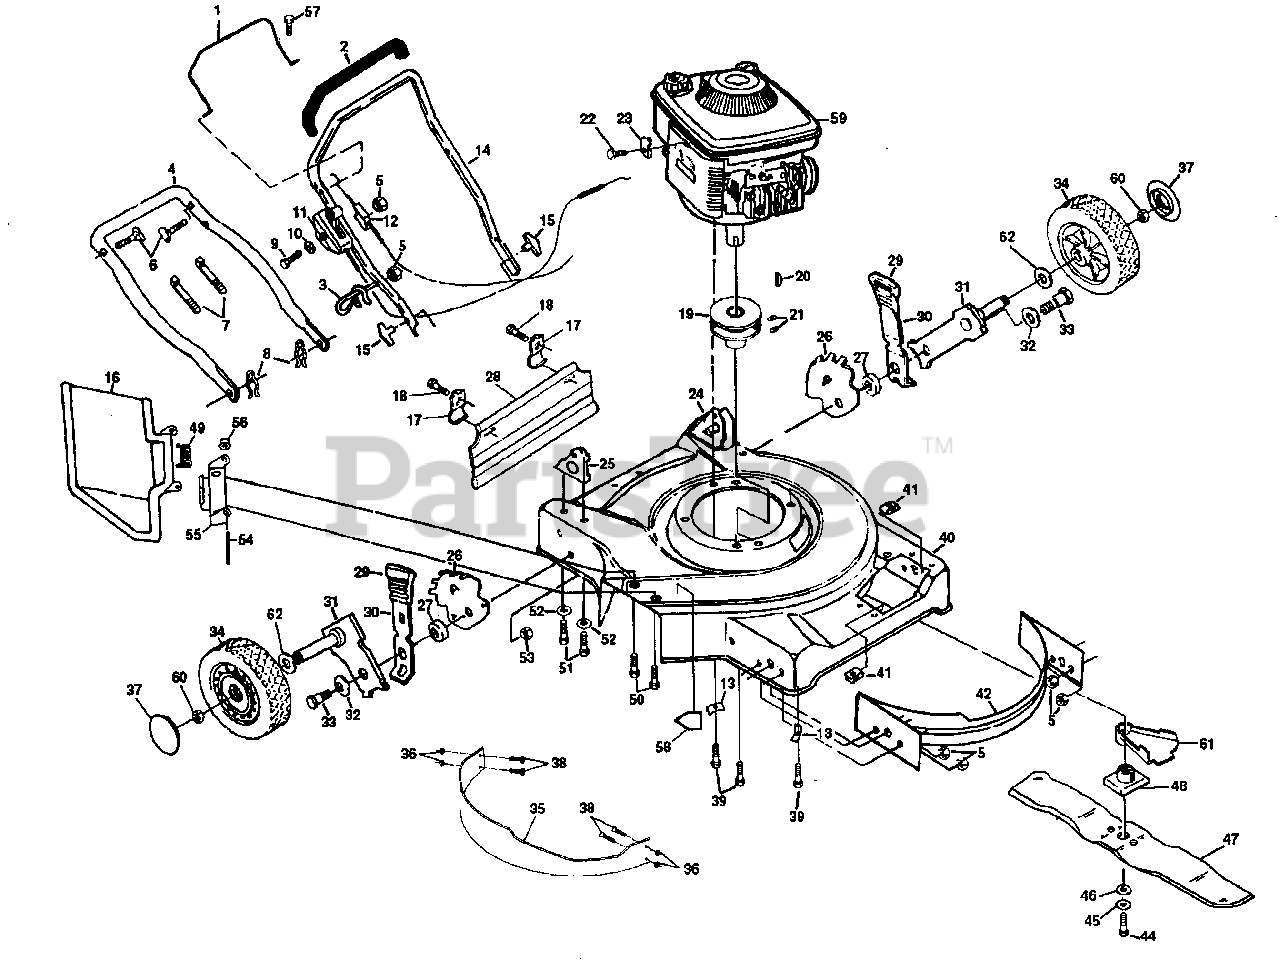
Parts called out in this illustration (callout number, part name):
1	Control Bar
2	Handle Grip (AYP part number)
3	Rope Guide
4	Lower Handle (AYP part number)
5	Locknut 1/4-20 (AYP part number)
6	Handle Bolt (AYP part number)
7	Wire Tie (AYP part number)
8	Hairpin Cotter (AYP part number)
9	Machine Screw 1/4-20 x 2-1/8 (AYP part number)
10	Washer 9/32 x 5/8 x 1/16 (AYP part number)
11	Deluxe Throttle Control (AYP part number)
12	Engine Zone Control Cable
13	Engine Washer (AYP part number)
14	Upper Handle (AYP part number)
15	Handle Knob (AYP part number)
16	Discharge Guard
17	Bracket Skirt (AYP part number)
18	Screw Hex Washer Head (AYP part number)
19	Engine Pulley (AYP part number)
20	Hi Pro Key #HP-505 (AYP part number)
21	Set Screw 1/4-20 x 5/16 (AYP part number)
22	Thread Rolling Screw #10-32 x 5/8 (AYP part number)
23	Cable Clamp (Engine) (AYP part number)
24	Handle Bracket Assembly (Left) (AYP part number)
25	Handle Bracket Assembly (Right) (AYP part number)
26	Wheel Adjuster Bracket (AYP part number)
27	Spacer (AYP part number)
28	Rear Skirt (AYP part number)
29	Selector Knob
30	Selector Spring (AYP part number)
31	Axle Arm Assembly (AYP part number)
32	Belleville Washer 1/2 (AYP part number)
33	Shoulder Bolt 3/8-16 (AYP part number)
34	Wheel & Tire Assembly (Rear) 8.00 x 1.75
35	Baffle Mulcher (AYP part number)
36	Locknut (AYP part number)
37	Hubcap (AYP part number)
38	Screw (AYP part number)
39	Hex Head Thread Rolling Screw 3/8-16 x 1-1/8 (AYP part number)
40	Lawn Mower Housing Kit (Inc. 58)
41	U-type Speed Nut (AYP part number)
42	Front Baffle (AYP part number)
44	Hex Head Machine Screw 3/8-24 x 1-3/8
45	Helical Lockwasher 3/8 (AYP part number)
46	Hardened Washer (AYP part number)
47	22" Blade (AYP part number)
48	Blade Adapter
49	Torsion Spring (AYP part number)
50	Hex Head Thread Rolling Screw w/Sems 1/4-20 (AYP part number)
51	Thread Cutting Screw 5/16-18 x 3/4 (AYP part number)
52	Washer 5/16 (AYP part number)
53	Locknut 3/8-16 (AYP part number)
54	Hinge Rod (AYP part number)
55	Housing Bracket (AYP part number)
56	Push-on Speed Nut (AYP part number)
57	Self-tapping Screw #10-24 x 5/8 (AYP part number)
58	Danger Decal (Housing) (AYP part number)
60	Locknut (AYP part number)
61	Shield Debris
62	Wave Washer (AYP part number)
